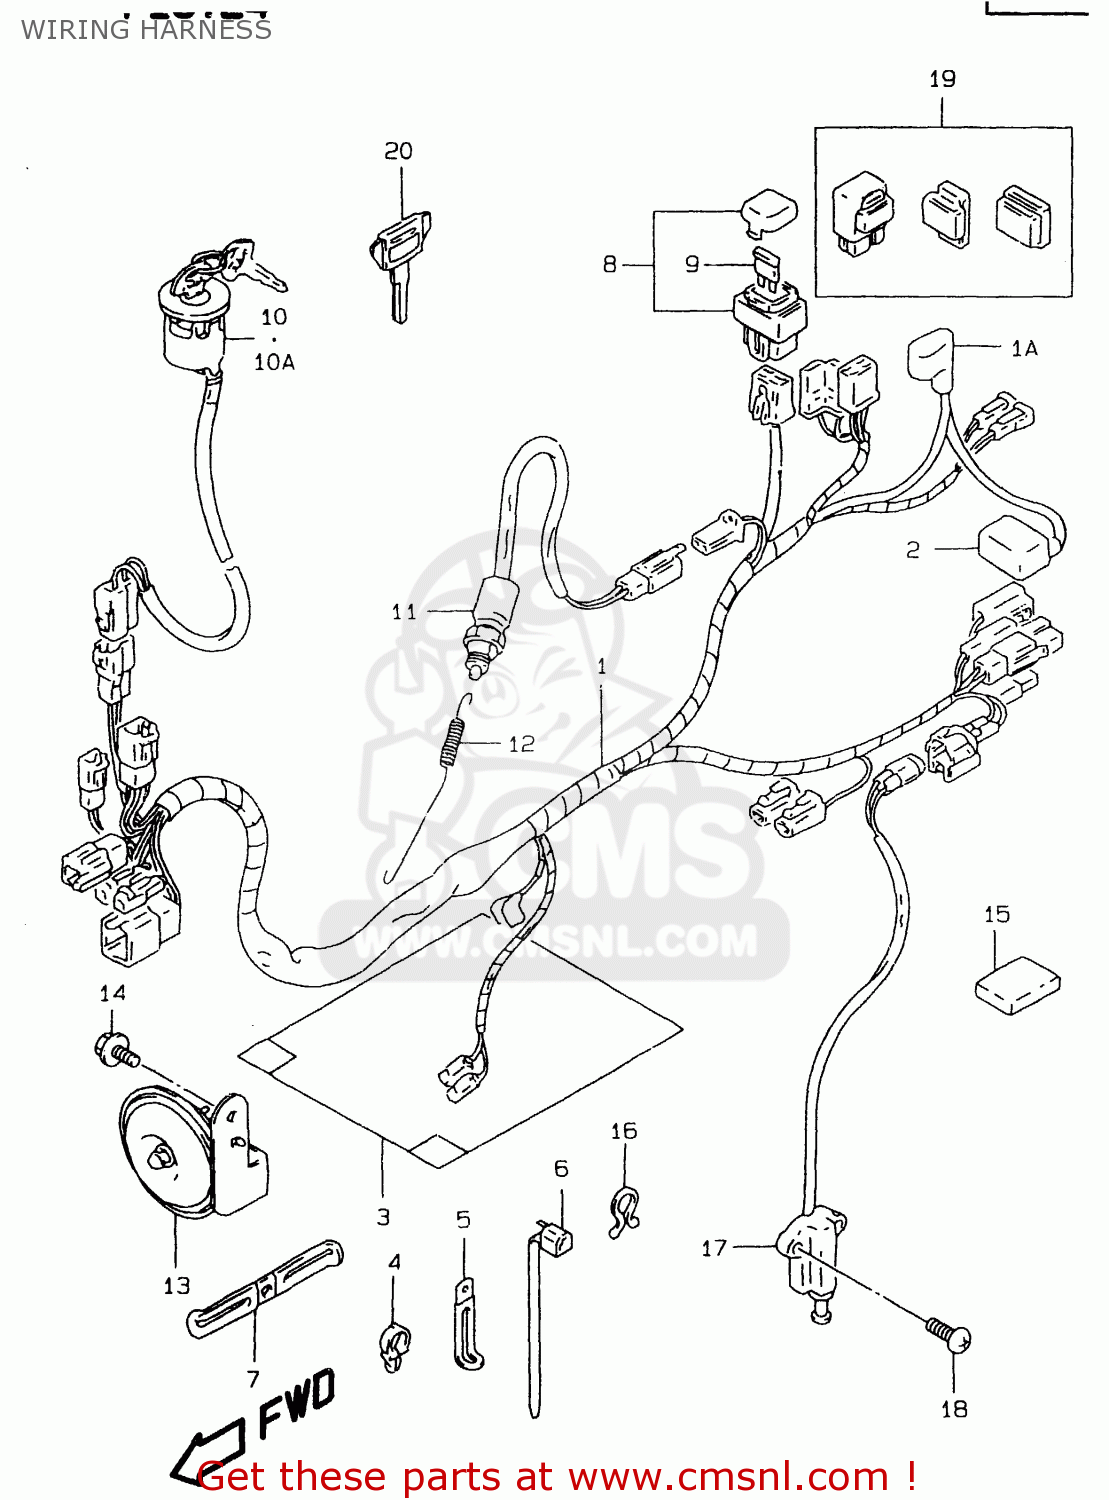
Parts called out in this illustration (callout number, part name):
1	HARNESS,WIRING
1A	CAP,STARTER RELAY
2	CAP,BATTERY PLUS
3	COVER,WIRING HARNESS
4	CLAMP
5	CLAMP(L:80)
6	CLAMP(L:125)
7	CLAMP,STARTER MOTOR LEAD
8	BOX ASSY,FUSE
9	FUSE(20A)
10	SWITCH ASSEMBLY,IGNITION
10A	SWITCH ASSY,IGNITION
11	SWITCH ASSY,STOP LAMP
12	SPRING
13	HORN ASSY
14	BOLT
15	PROTECTOR,WIRING HARNESS
16	CLIP(ID:11.5)
17	SWITCH ASSY,SIDE STAND
18	SCREW
19	RELAY ASSY
20	KEY,BLANK(TYPE:C)
